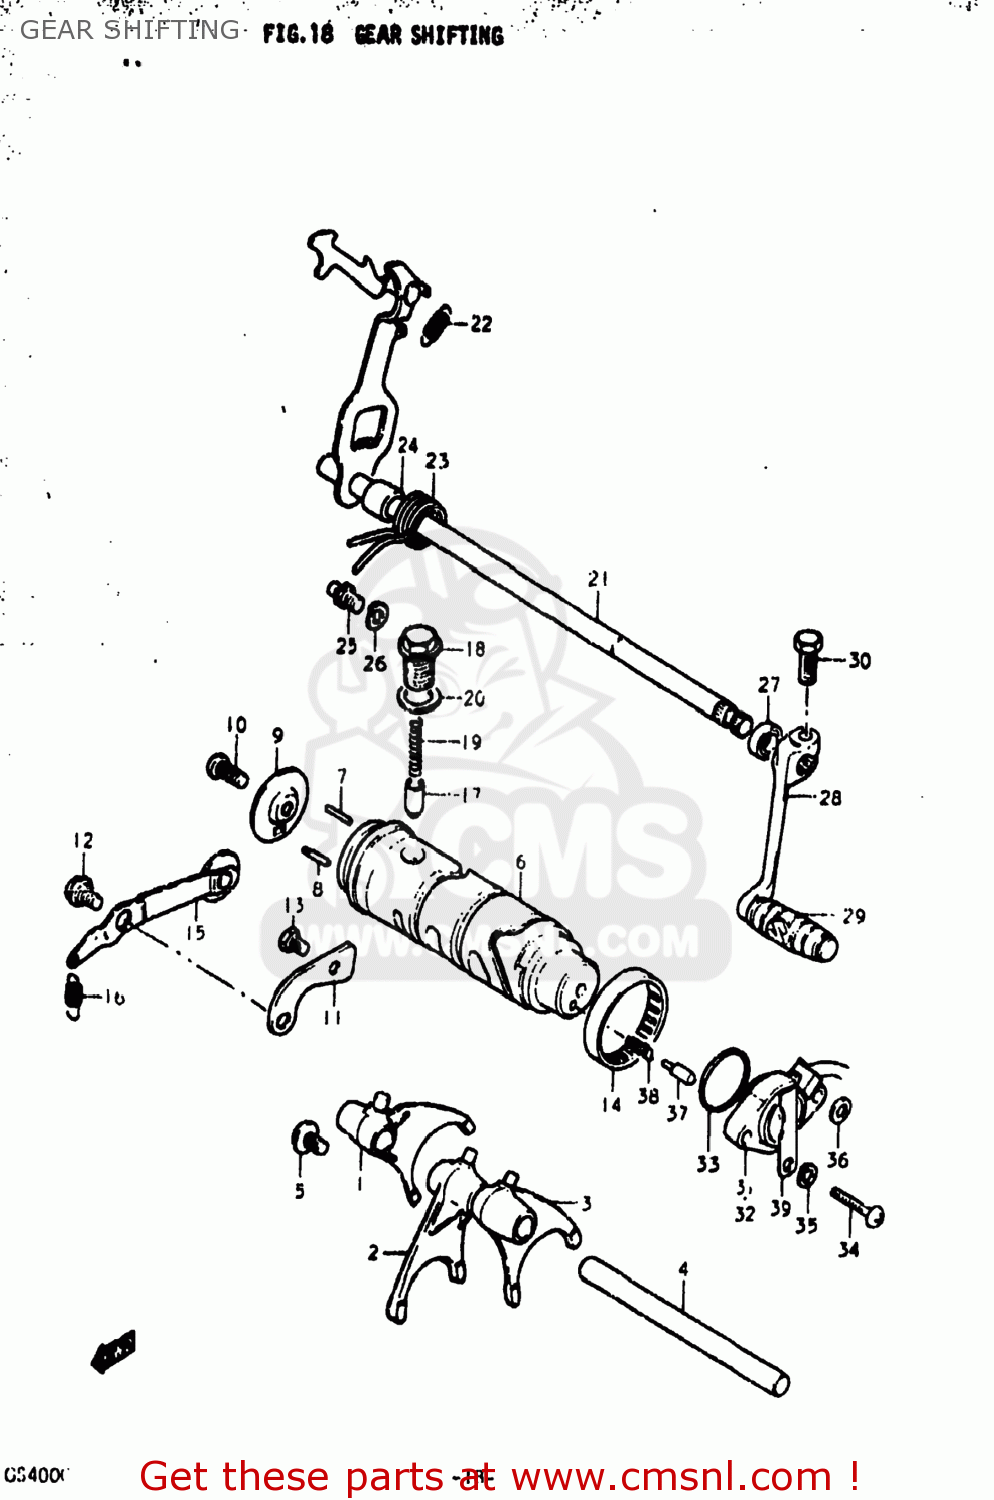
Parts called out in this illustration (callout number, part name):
1	FORK,GEAR SHIFT NO.1
2	FORK,GEAR SHIFT NO.2
3	FORK,GEAR SHIFT NO.2
4	SHAFT,GEAR SHIFT FORK
5	SCREW
6	CAM,GEAR SHIFT
7	PIN(4X18.5)
8	PIN
9	RETAINER,GEAR SHIFT CAM DR PIN
10	SCREW
11	GUIDE,GEAR SHIFTING CABLE
12	BOLT
13	BOLT
14	BEARING(40X47X12)
15	STOPPER,GEAR SHIFT CAM NO.1
16	SPRING
17	STOPPER,GEAR SHIFTING
18	BOLT,GEAR SHAFT CAM STOPPER
19	SPRING
20	GASKET(14X19.2X2) (NAS)
21	SHAFT,GEAR SHIFT
22	SPRING
23	SPRING
24	SPACER (17X33X12.5)
25	STOPPER,GEAR SHIFT CAM
26	LOCK WASHER
27	OIL SEAL
28	LEVER ASSY,GEAR SHIFT
29	RUBBER,GEAR SHIFT PEDAL
30	BOLT
31	BASE ASSEMBLY,NEUTRAL SWITCH TERMINAL
32	TERMINAL BASE,NEUTRAL SWITCH
33	O-RING (D:2.4 ID:26.2)
34	SCREW
35	LOCK WASHER
36	WASHER
37	PIN(5X15.5)
38	SPRING
39	CLAMP,GENERATOR LEAD WIRE
